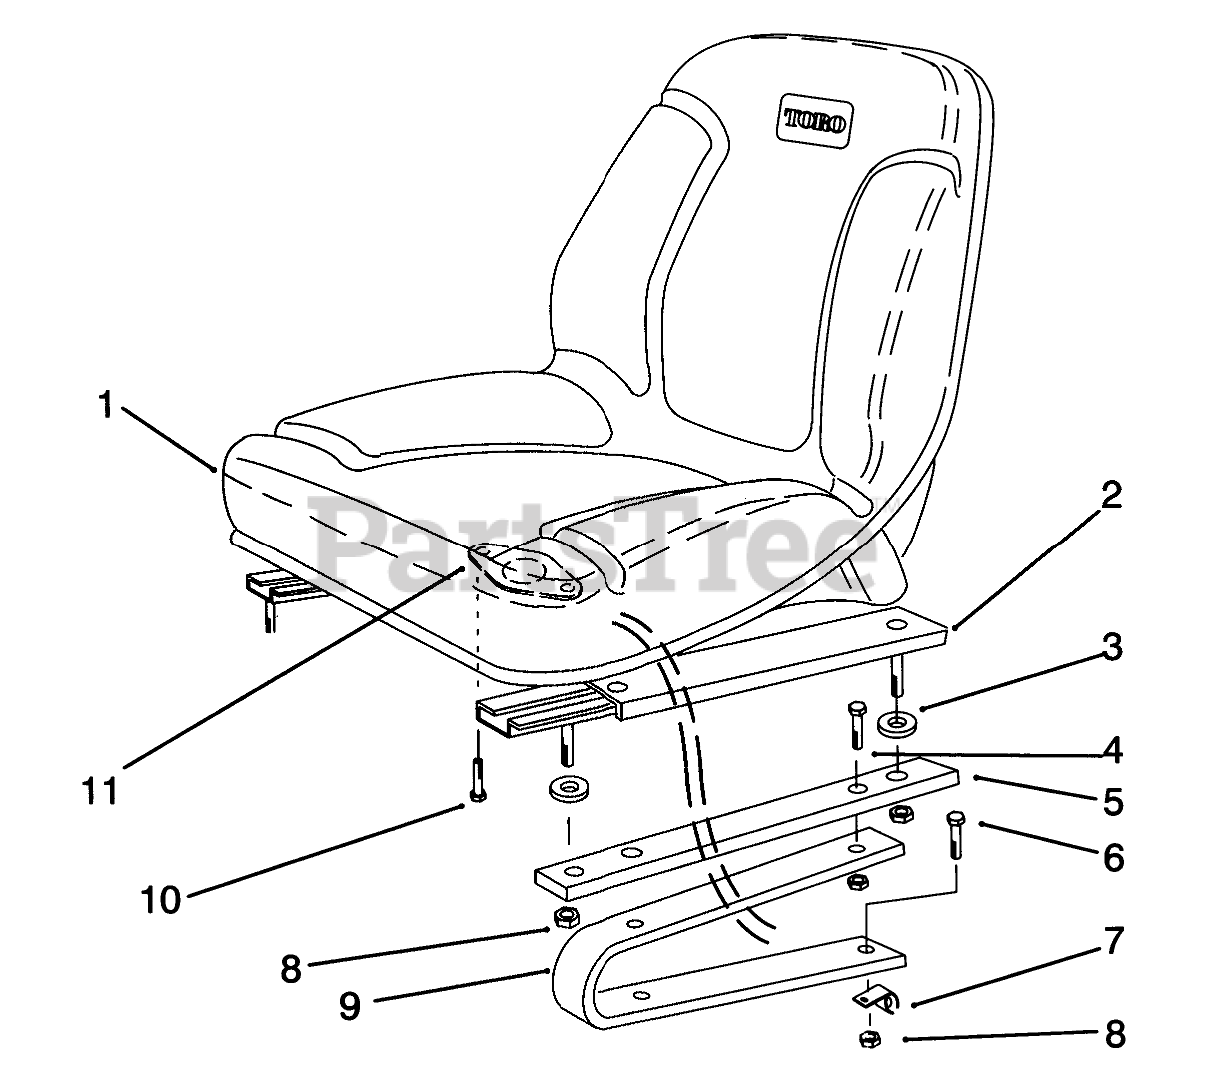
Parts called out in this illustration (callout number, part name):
1	SEAT ASM
2	ADJUSTER-SEAT, LH
3	SPACER-NYLON
4	SCREW-HH
5	Plate-Adapter, Seat
6	SCREW-HH
7	CLAMP-R
8	NUT-LOCK, NI
9	Seat Spring
10	SCREW-HH
11	SWITCH-SEAT
